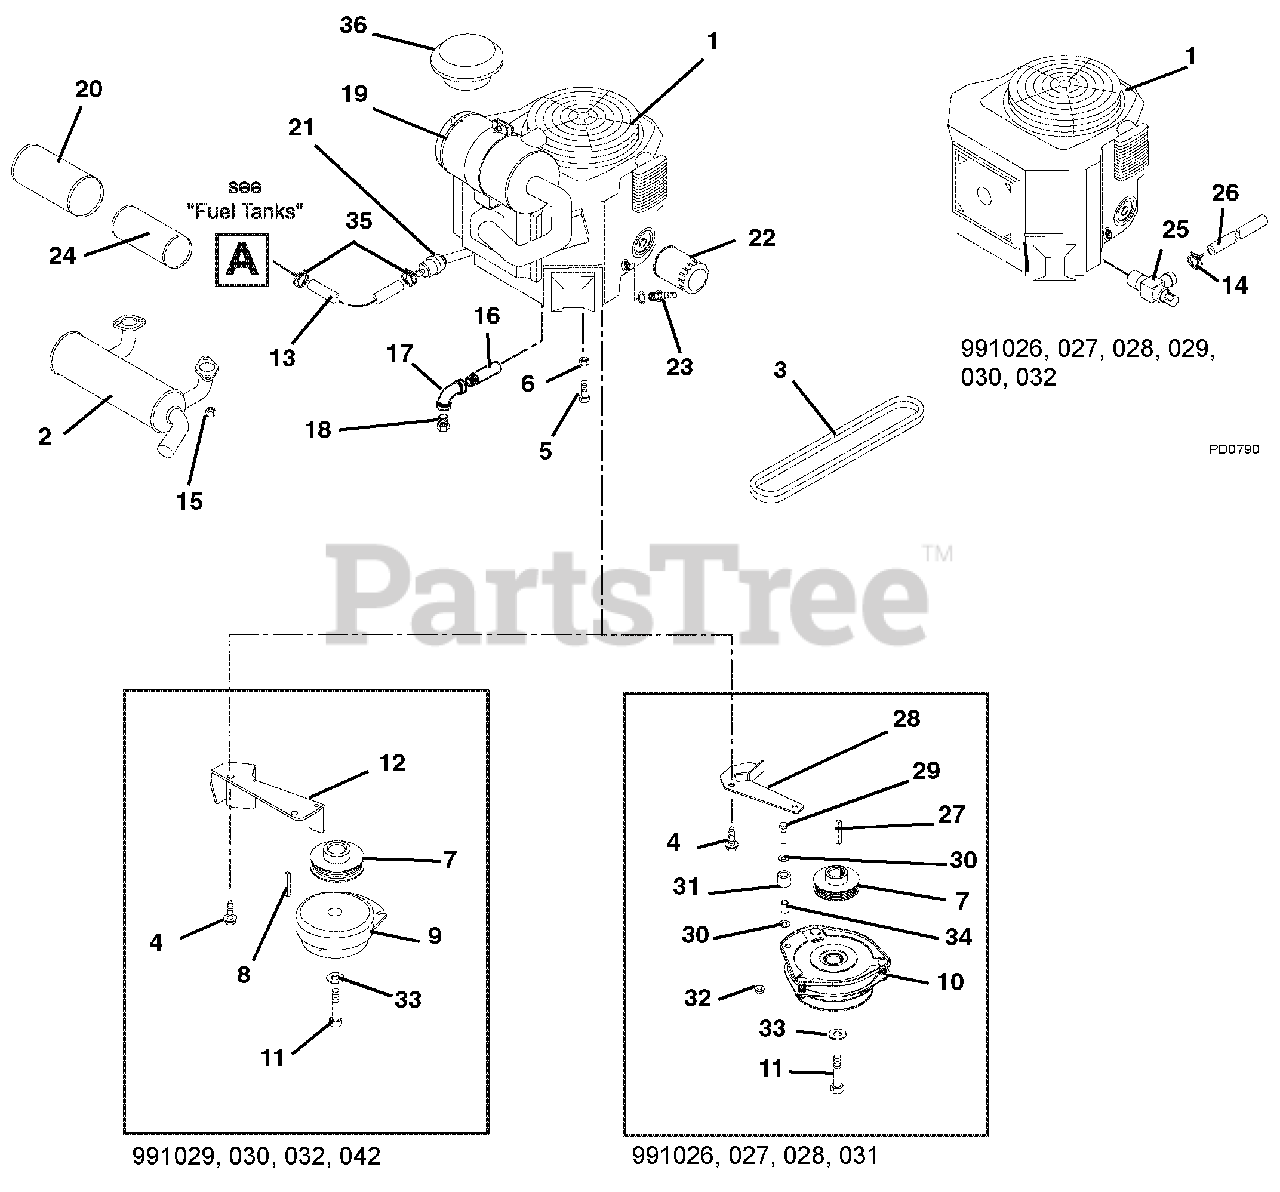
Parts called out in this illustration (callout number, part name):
1	Engine, Kawasaki 19HP (991029, 032)
2	Muffler, Kohler (991031, 042)
3	V-Belt, HA 54.50 x .535 (991029, 030, 032, 042)
4	Bolt, Tapping .36-16X1.5 PH TRX YZ (991026, 027, 028, 029, 030, 032)
5	Bolt, Hex .31-18 x 1.50 Grade 5 (991026, 027, 028, 029, 030, 032)
6	Nut, Locking Top Flange .31-18 (991026, 027, 028, 029, 030, 032)
7	Sheave, 4.831 x 1.127
8	Key, Square .25 x .625 x .25 SAE 8630 or SAE 1035
9	Clutch, Electric (991029, 030, 032, 042)
10	Clutch, Electric (991026, 027, 028, 031)
11	Bolt, Hex .44-20 x 2.50 Grade 5 (991026, 027, 028, 031)
12	Clutch Stop (991029, 030, 032)
13	Gas Line, Bulk .25 ID
14	Hose, Clamp
15	Nut, M8-1.25
16	Nipple (991031, 042)
17	Elbow .375-18 (991031, 042)
18	Pipe Plug (991031, 042)
19	Assembly, Air Cleaner (991026, 027, 028, 031)
20	Filter, Outer Element (991026, 027, 028, 031)
21	Fuel Filter, Kohler (991031, 042)
22	Oil Filter, Kohler (991031, 042)
23	Spark Plug, Kohler (991031, 042)
24	Filter, Inner Element (991026, 027, 028, 031)
25	Drain, 1/2" Oil (991026, 027, 028, 029, 030, 032)
26	Tube, Oil Drain (991026, 027, 028, 029, 030, 032)
27	Key, Square .25 x 3.50 x .25 SAE (991026, 027, 028, 030)
28	Clutch Stop (991026, 027, 028, 031)
29	Bolt, Hex .38-16 x 1.50 Grade 5 (991026, 027, 028, 031)
30	Washer, Flat-Steel .406 x .812 x .065 (991026, 027, 028, 031)
31	Bumper, Rubber .62 x 1.0 x .88 LG (991026, 027, 028, 031)
32	Nut, Locking-Top-Flange .38-16 (991026, 027, 028, 031)
33	Washer, Flat Steel .469 x 2.00 x .25 (991026, 027, 028, 031)
34	Bushing, .407 x .625 x .813 (991026, 027, 028, 031)
35	Clamp, Hose Wire .490/.510 x .116
36	Cap, 2" Air Cleaner Intake
